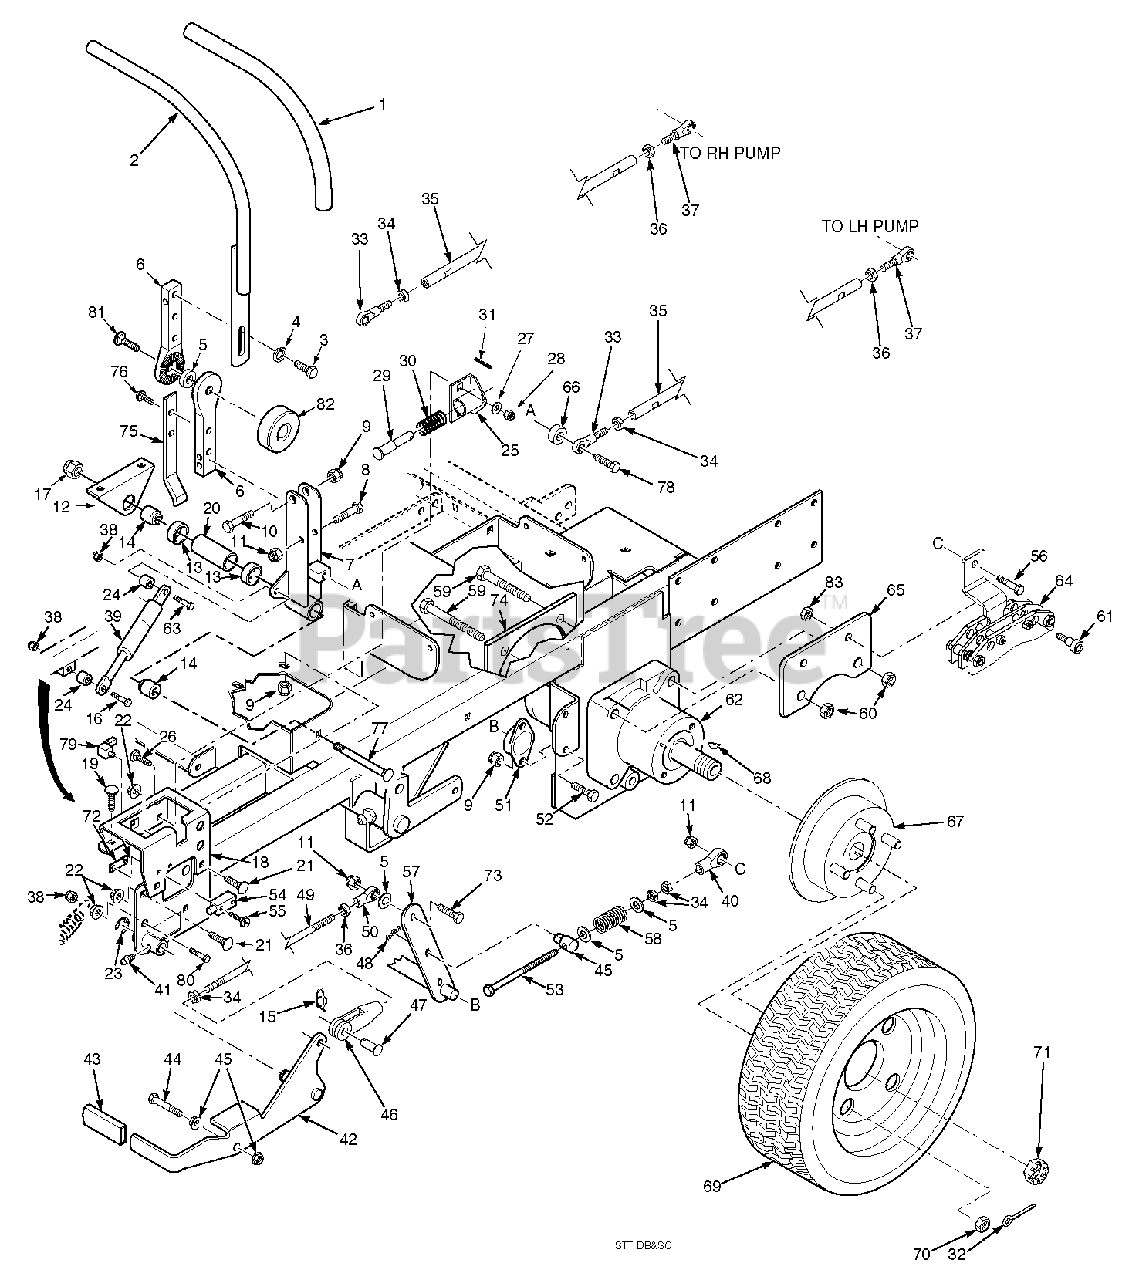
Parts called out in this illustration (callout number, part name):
1	Grip, Handle Bar
2	Handle Bar, LH
3	Bolt, Hex Hd. 5/16-18 x 1"
4	Lockwasher, 5/16"
5	Rubber Spacer
6	Bar, Control Lever
7	Control Lever Weldment, LH
8	Bolt, Hex Hd. 5/16-18 x 2"
9	Nut, Hex Elastic Stop 5/16-18
10	Bolt, Hex Hd. 3/8-16 x 2"
11	Nut, Hex Elastic Stop
12	Mount, Control Linkage
13	Ball Bearings, Neutral Return
14	Spacer
15	Pin, Rue Cotter 3/8" Dia.
16	Bolt, Hex Hd., 5/16-18 x 2.75 Zinc
17	Nut, Hex Elastic Stop 5/8-11
18	Bracket, Control Lever LH
19	Bolt, Carriage 5/16-18 x 1"
20	Spacer, Bearing
21	Bolt, Carriage 5/16-18 x 3/4"
22	Nut, Hex Serr. Flng. 5/16-18
23	Ring, Retaining 5/8" External "E"
24	Spacer
25	Bracket, Neutral Return
26	Bolt, Carriage 1/4-20 x 3/4"
27	Flatwasher, 1/4"
28	Nut, Hex Elastic Stop 1/4-20
29	Pin, Retaining Spring
30	Spring
31	Roll Pin, Spring 5/32 x 3/4"
32	Pin, Cotter 9/16 x 1-1/2"
33	Rod End, Male 3/8-24 RH Thread
34	Nut, 3/8-24 RH Thread
35	Tube, Control Link Liquid-Cooled Engine
36	Nut, Hex 3/8-24 LH Thread
37	Rod End, Male 3/8-24 LH Thread
38	Locknut, 5/16-18, Elastic Stop
39	Gas Damper
40	Rod End, 3/8-24 RH Female
41	Grease Fitting
42	Lever, Parking Brake
43	Grip, Parking Brake
44	Bolt, Hex Hd. 3/8-16 x 2-3/4"
45	Swivel Joint
46	Clevis, Traction Control
47	Pin, Clevis 3/8-16 x 1-1/16"
48	Hair Pin Cotter
49	Rod, Parking Brake
50	Rod End, LH Thread
51	Bushing, Self Align
52	Bolt, Hex Hd. 5/16-18 x 3/4"
53	Bolt, Hex Hd 3/8-24 x 5-1/2"
54	Switch
55	Screw, Hex Sltd. Wshr. Hd. #10 32 x 3/4"
56	Brake Linkage, LH
57	Bellcrank, Brake Actuator
58	Spring
59	Bolt, Hex Hd. 1/2-13 x 2-3/4"
60	Locknut, Hex 1/2-13 Center Lock
61	Bolt, Shoulder 3/8-16 x 2-1/2"
62	Wheel Motor, Parker
63	Bolt, Hex Hd., 5/16-18 x 1.75", Zinc
64	Brake Caliper
65	Mounting Bracket, Brake
66	Spacer
67	Wheel Hub/Disk Brake Assembly
68	Key, Woodruff 5/16 x 1"
69	Wheel Assembly 24 x 12-12 Turf Master
70	Lug Nut, 1/2-20
71	Nut, Hex Castle
72	Threaded Plate
73	Bolt, Hex Hd. 3/8-16 x 1-1/2"
74	Plate Weldment, Motor Backing
75	Actuator Switch
76	Bolt, Hex Serr. Flng. 5/16-18 x 3/4"
77	Bolt, Carriage 3/8-16 x 4-3/4"
78	Bolt, Hex Hd. 3/8-16 x 1"
79	Switch
80	Bolt, Hex Hd. 3/8-16 x 1-1/4" Grd. 8
81	Bolt, Carriage 5/16-18 x 1-1/2"
83	Nut, Center Lock 3/8-16
